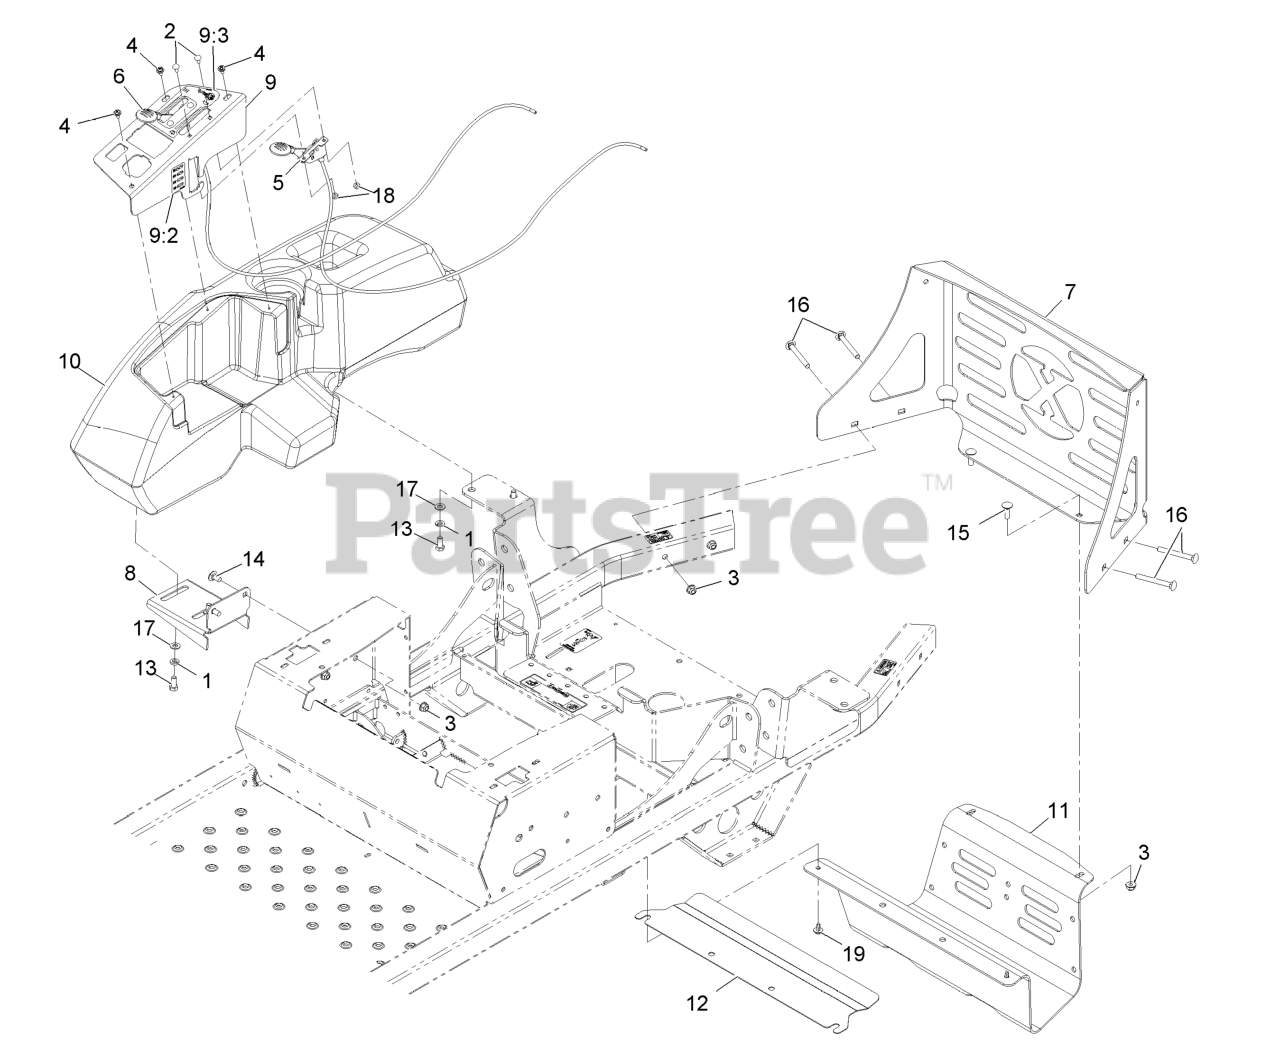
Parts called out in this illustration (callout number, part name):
1	WASHER-LOCK
2	BOLT-CARR
3	NUT-HF, NI
4	SCREW-PPH
5	CONTROL,THROTTLE
6	CONTROL,CHOKE
7	PANEL,REAR GUARD
8	BRACKET-TANK AND FENDER
9	ASM,CONTROL PANEL W/DECAL
9:2	DECAL,FUSE BLOCK
9:3	DECAL-THROTTLE CHOKE
10	CONSOLE,RH
11	GUARD-MUFFLER
13	SCREW-HH
14	SCREW-CARR
15	BOLT-CARR
16	SCREW-CARR
17	WASHER-PLAIN
18	NUT-LOCK, NI
19	SCREW-HHFTF
